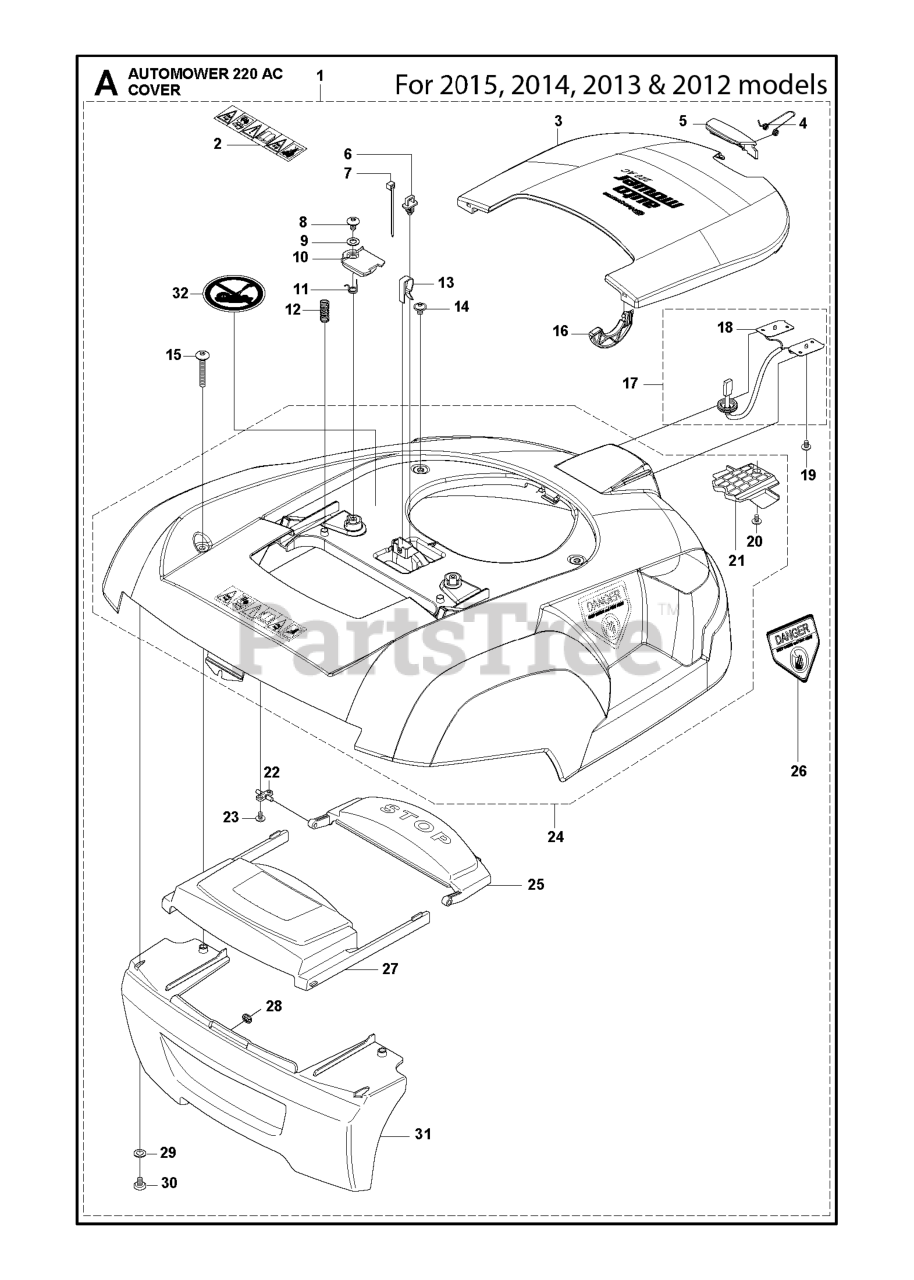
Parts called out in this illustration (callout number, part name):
1	BODY KIT FOREST GREEN, 220 AC
2	LABEL WARNING
5	HEIGHT ADJ. COVER LATCH
6	BRACKET FOR BAND
8	SCREW SILVER 10MM
13	CLIP RETAINER
15	SCREW IHPANM
17	WIRING ASSY
18	THIN PLATE
19	SCREW WHITE 6MM
20	SCREW 12MM
23	SCREW SILVER 10MM
24	BODY KIT INCLUDING NEW BODY &
30	SCREW 14MM
31	BUMPER, COVER
32	LABEL WARNING KIT 10 PCS
